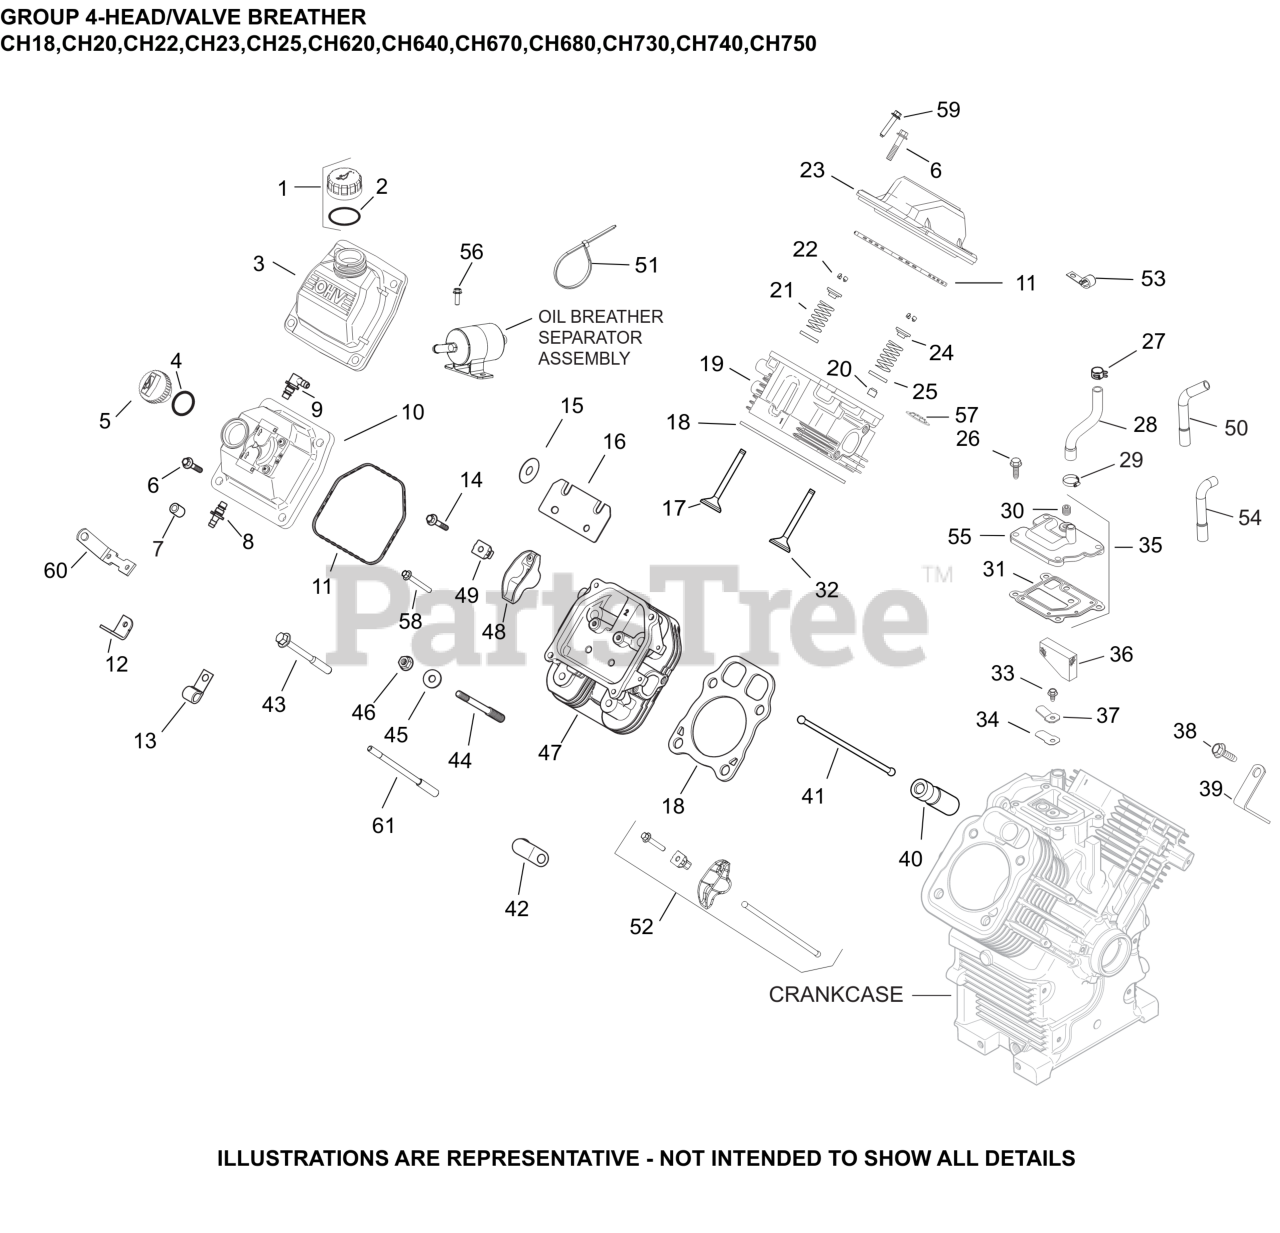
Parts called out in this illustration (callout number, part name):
5	CAP ASSY, OIL FILL (YELLOW)
8	KIT, STRAIGHT FITTING
9	KIT, 90 DEG. FITTING
10	KIT,VALVE COVER-FUEL PUMP
11	O-RING (YELLOW), VALVE CO
17	VALVE, EXHAUST
17	VALVE, EXHAUST (.25)
18	KIT, GASKET CYLINDER HEAD
19	KIT, CYLINDER HEAD (#1)-(#2481803S)
20	SEAL, VALVE BAND
21	SPRING, VALVE
22	KIT, RETAINER
23	KIT, VALVE COVER-PLAIN (PLASTIC)
24	CAP, VALVE SPRING
25	RETAINER, SPRING
26	SCREW, THREAD FORMING
27	SPRING CLAMP, HOSE
28	KIT, BREATHER HOSE AND CLAMP
31	GASKET, BREATHER
32	VALVE, INTAKE (STD)
32	VALVE, INTAKE (.25)-(#DSC)
33	SCREW, FLG THD FRM M5X.8X10
34	REED, BREATHER
36	FILTER, BREATHER
37	RETAINER, REED
40	LIFTER, VALVE HYDRAULIC-USE 25 351 11-S
41	ROD, PUSH
44	STUD, M8X1.25
45	WASHER, FLAT 8.6 MM
46	NUT, FLG M8X1.25
47	KIT, CYLINDER HEAD (#2)-(#2481804S)
48	ARM, ROCKER
49	PIVOT, ROCKER ARM
52	KIT, VALVE TRAIN
55	COVER, BREATHER
57	RETAINER, VALVE GUIDE (KM)
58	SCREW, HEX FLANGE
59	SCREW, HEX FLANGE (M6 X 31.625 DOG PT)
60	STRAP, LIFTING
